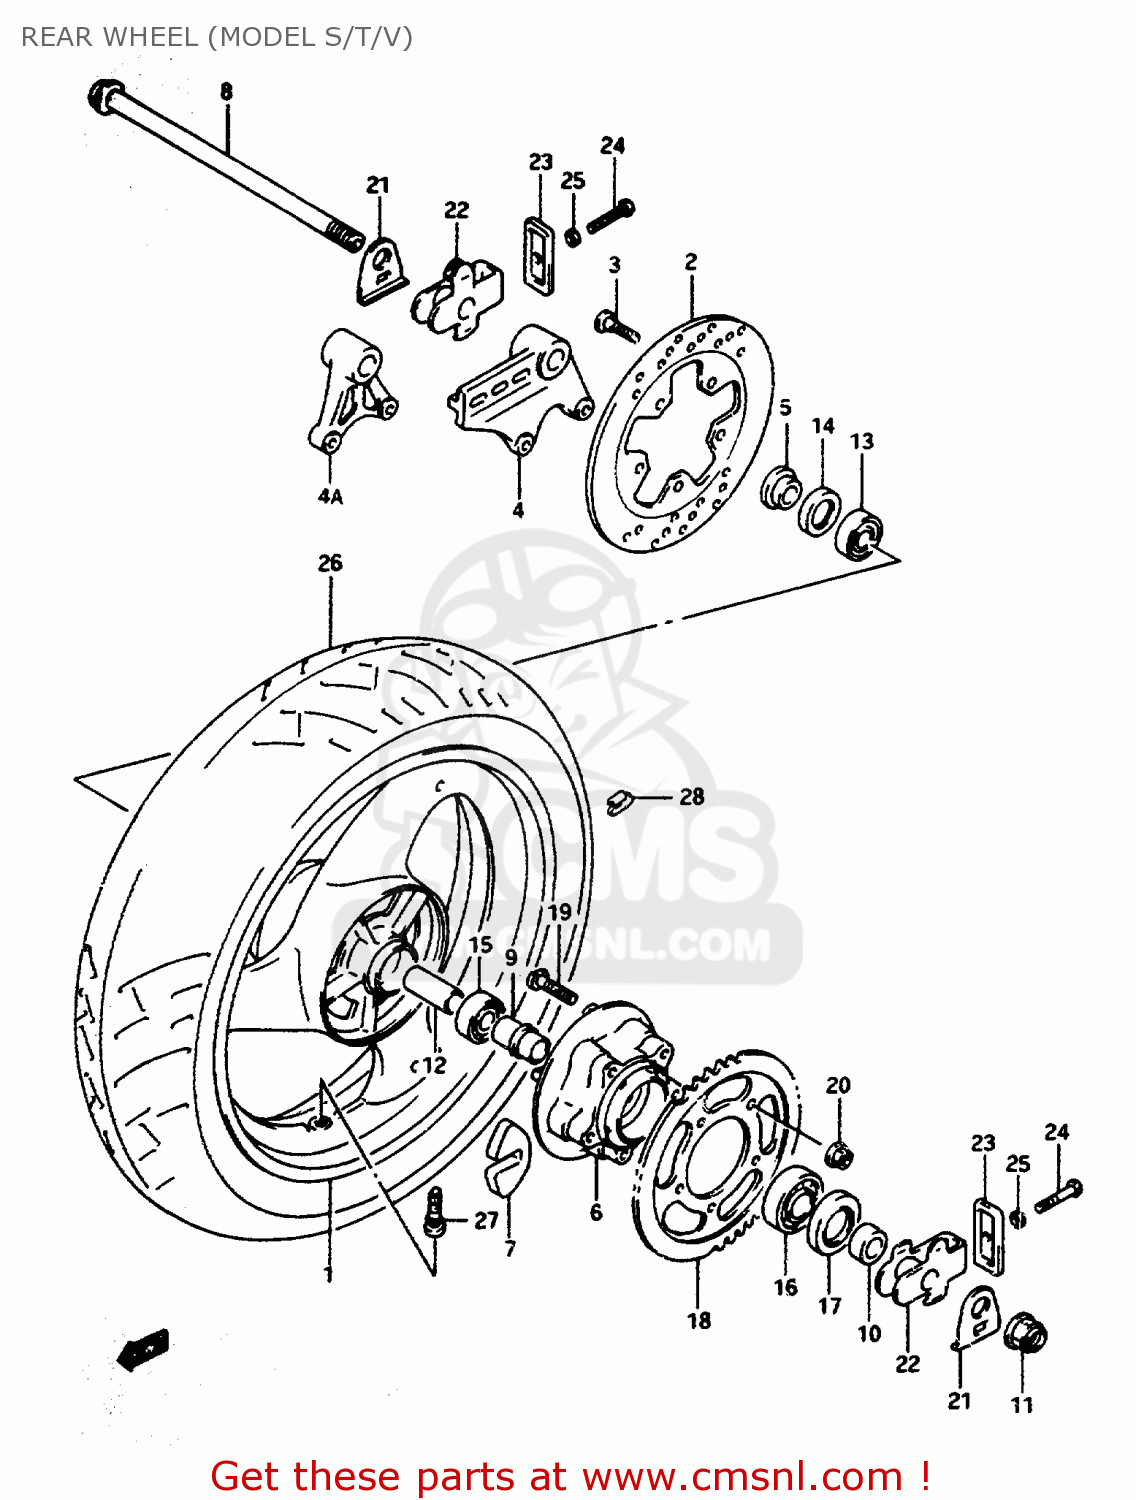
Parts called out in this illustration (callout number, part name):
1	WHEEL,REAR
2	DISC,RR BRAKE
3	BOLT 8X33
4	BRACKET,RR CALIPER
4A	BRACKET,RR CALIPER
5	SPACER,RR AXLE,R
6	DRUM,RR SPROCKET
7	ABSORBER,RR HUB SHOCK
8	AXLE,RR
9	RETAINER,RR HUB BEARING
10	SPACER,RR AXLE,L
11	NUT ,18MM
12	SPACER(20.8X27.2X97)
13	BEARING
14	SEAL,OIL(28X47X7)
15	BEARING(20X47X14)
16	BEARING(25X62X17)
17	SEAL,OIL(35X62X8)
18	SPROCKET,RR(NT:43)
19	BOLT(10X47)
20	NUT
21	WASHER,CHAIN ADJUSTER
22	ADJUSTER,CHAIN
23	PLATE,CHAIN ADJUSTER GUIDE
24	BOLT(8X50)
25	WASHER
26	TIRE,REAR 160/70 ZR17
27	VALVE ASSEMBLY,WHEEL,TR412
28	BALANCER,WHEEL
